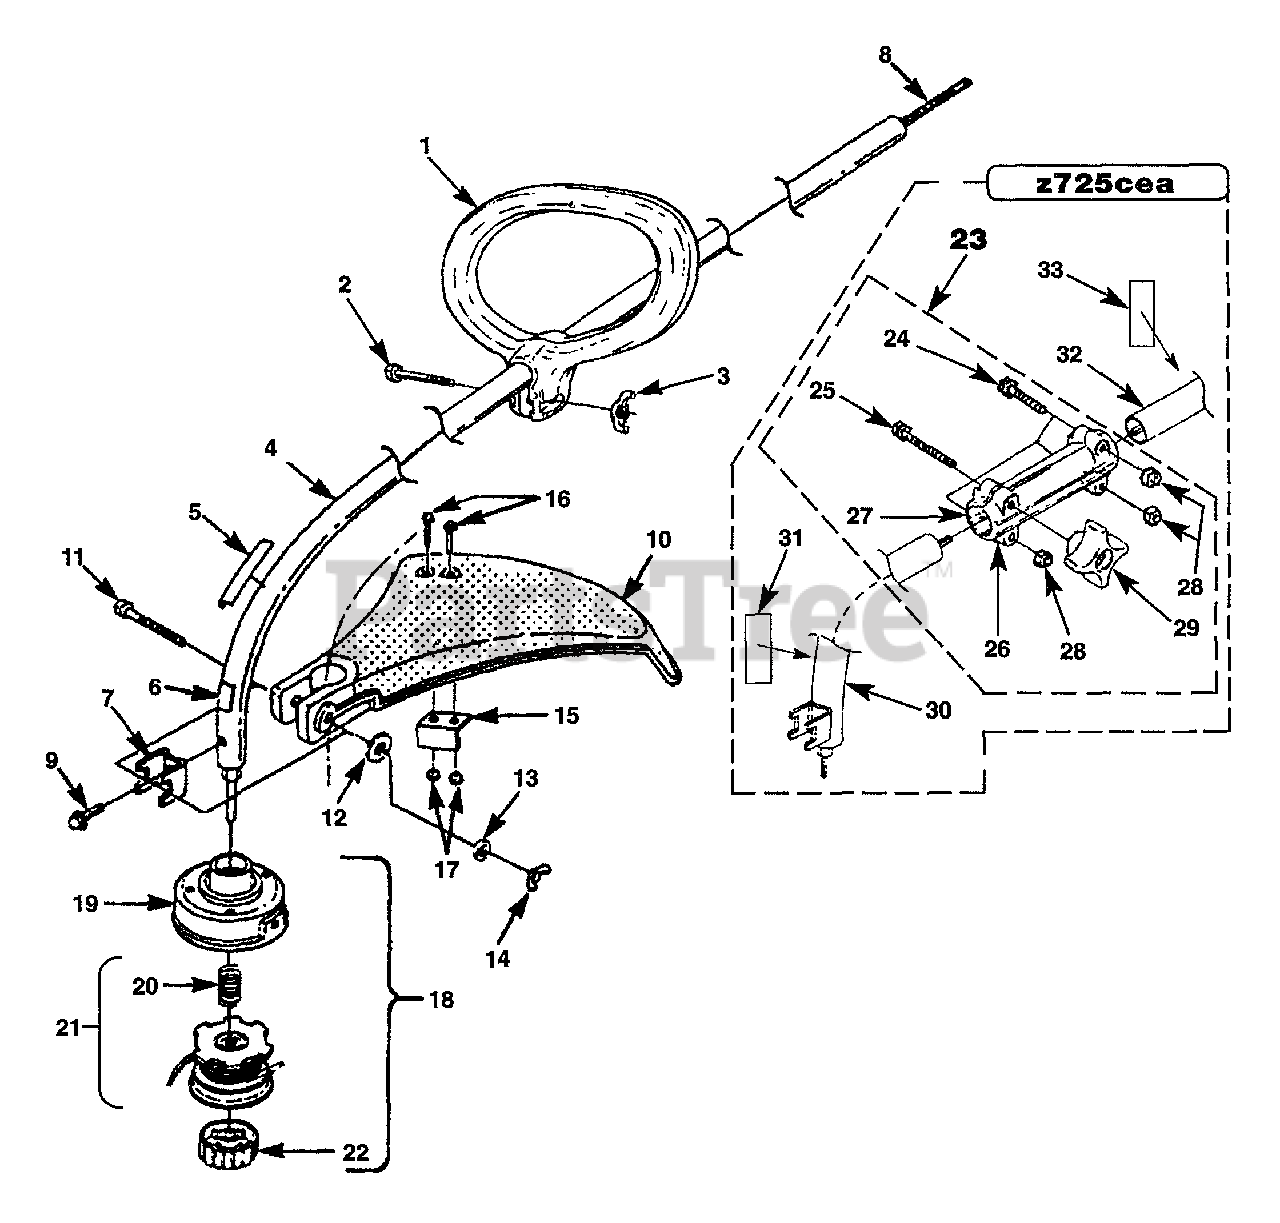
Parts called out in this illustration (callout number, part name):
1	FRONT HANDLE ("D")
2	SCREW-Cap Hex Hd. (10-24 X 2")
3	NUT-Wing (10-24)
4	HOUSING-Drive Shaft
5	DECAL-Starting Inst.
6	DECAL-Warning
7	CLAMP
8	SHAFT-Flexible
9	SCREW
10	DEFLECTOR & BLADE KIT (55 Degree)
11	SCREW-Cap Hex Hd. (1/4-20 X 2")
12	WASHER-Flat (1/4")
13	WASHER-Lock (1/4")
14	NUT-Wing (10-24)
15	BLADE-Cut-Off Kit
16	SCREW-Mech. Hex Hd. (10-24 X 7/8")
17	NUT-Hex (10-24)
18	STRINGHEAD-Complete (.080" Line)
19	HOUSING & EYELET (Dual Line)
20	SPRING-Compression
21	SPOOL & STRING (.080" Line)
22	RETAINER-Spool (R.H. Thread, Black)
23	COUPLER ASSEMBLY
24	BOLT-Hex Hd.
25	SCREW-Cap Hex (1/4-20 x 2")
26	SPLIT BOOM (L.H.)
27	SPLIT BOOM (R.H.)
28	NUT-Hex (1/4-20)
29	KNOB
30	DRIVE SHAFT HOUSING-Curved (Lower)
31	DECAL-Warning
32	DRIVE SHAFT HOUSING-Curved (Upper)
33	DECAL-Start Instructions
